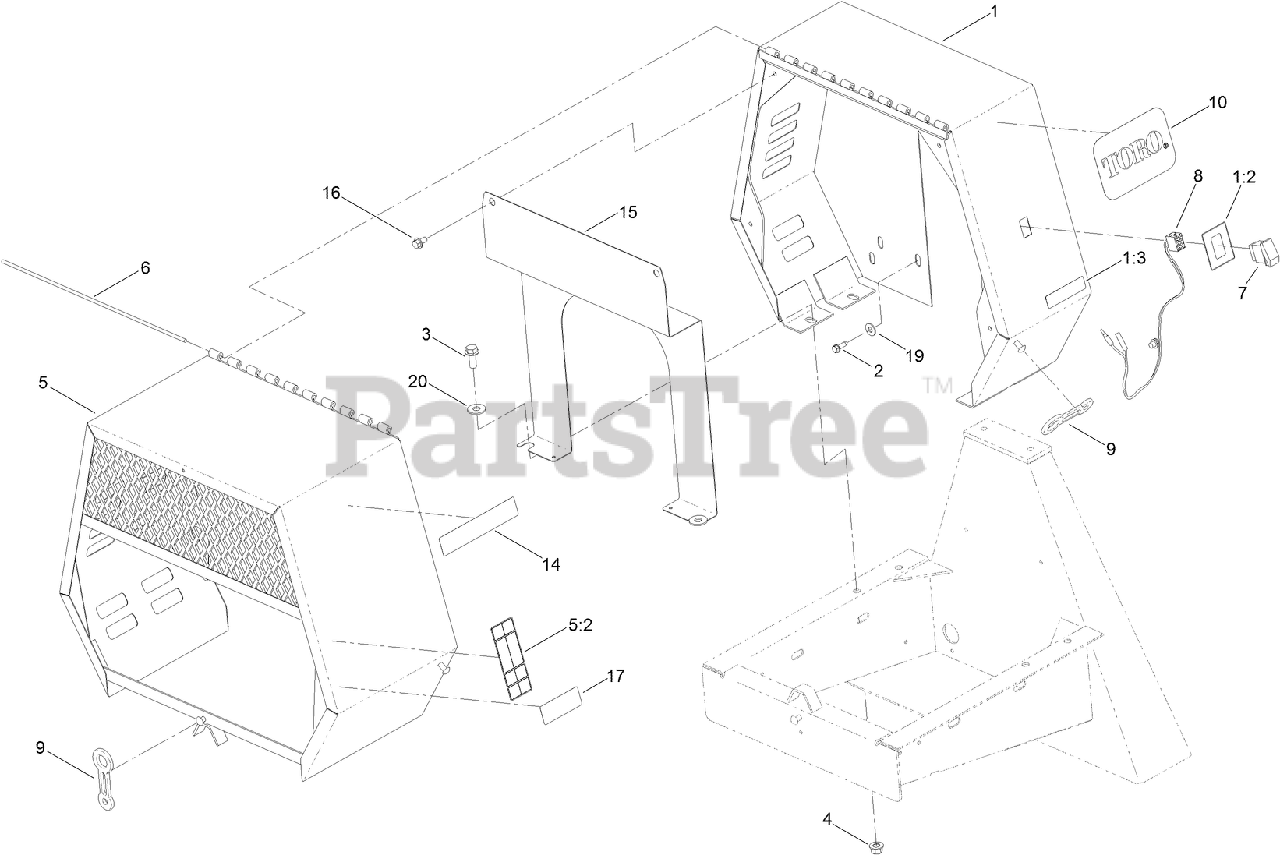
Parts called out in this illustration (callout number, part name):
1	STATIONARY COWL ASM
1:2	DECAL-STOP, ENGINE
1:3	DECAL-ARRESTER, SPARK
2	SCREW-HWHTF
3	SCREW-HHF
4	NUT-LOCK
5	MOVABLE COWL ASM
5:2	DECAL-WARNING
7	SWITCH
8	HARNESS-WIRE, MIXER
9	LATCH-RUBBER
10	DECAL
15	PLATE-ENGINE
16	SCREW-HWH
19	WASHER-FLAT
20	WASHER-FLAT
